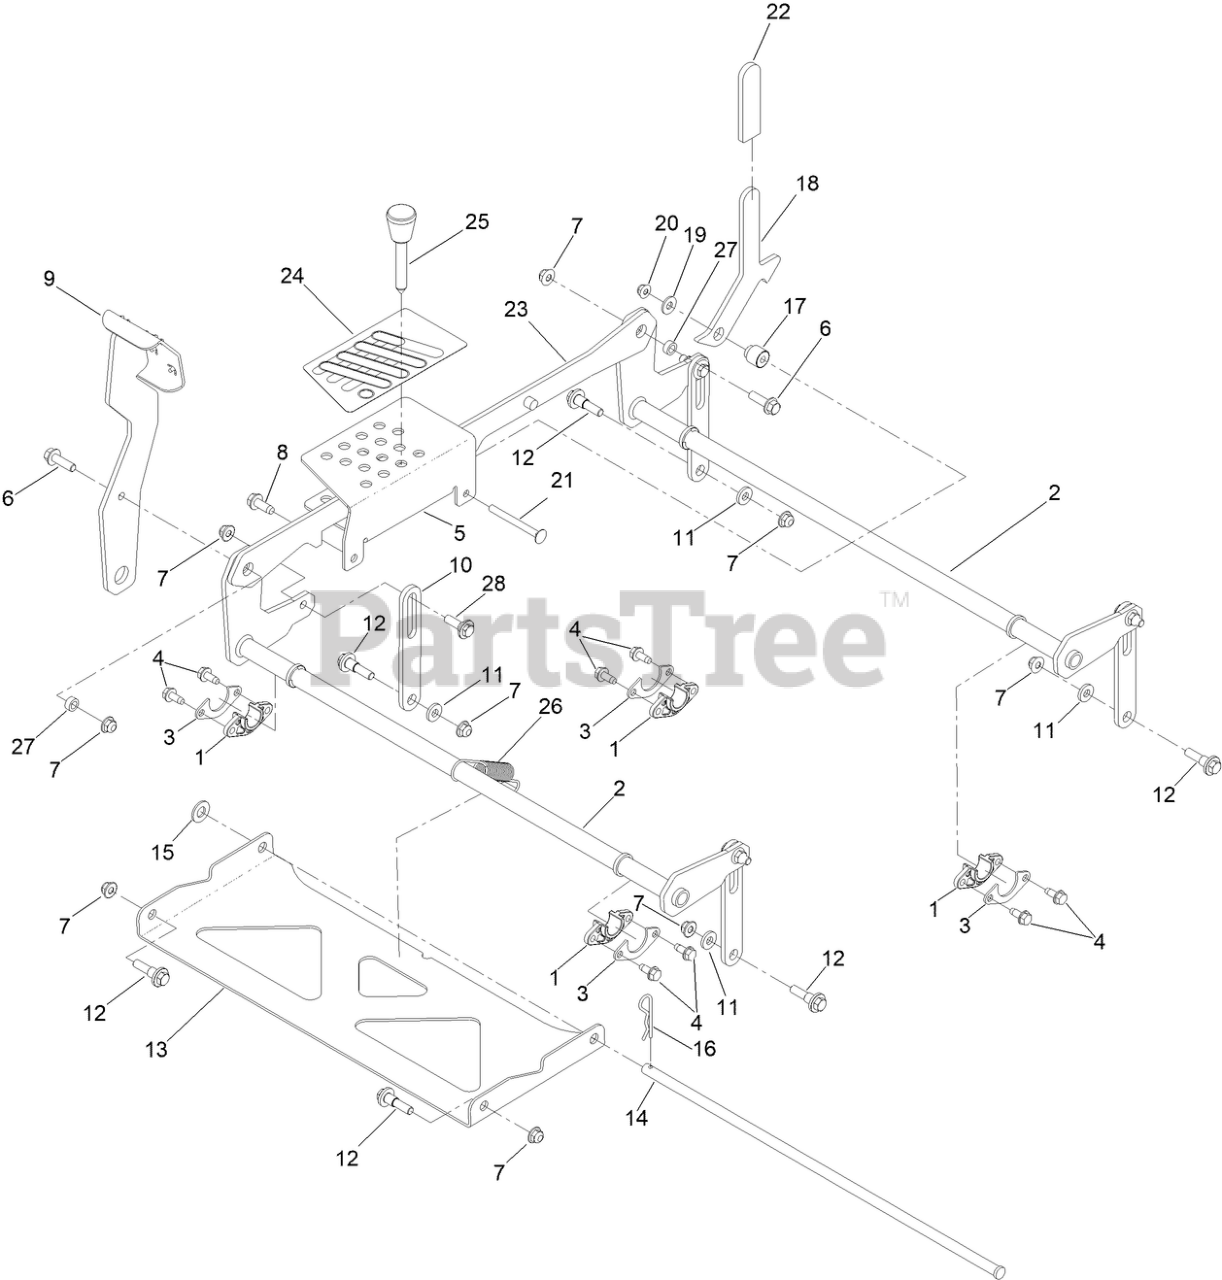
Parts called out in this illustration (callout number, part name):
1	BEARING-FLANGE
2	PIVOT ASM-DECKLIFT [RED]
3	GUSSET-DECK LIFT
4	SCREW-HWHTF
5	BRACKET-HOC
6	SCREW-HHF
7	NUT-HF, NI
8	SCREW-HWH
9	PEDAL ASM [RED]
10	LINK-HOC
11	SPACER-HUB, BLOWER
12	BOLT-SHOULDER
13	PAN-DECK PIVOT
14	PIN-DECK
15	WASHER-FLAT
16	PIN-HAIR
17	SPACER-STEPPED
18	PLATE-TRANSPORT LOCK
19	WASHER-PLAIN
20	NUT-HF
21	SCREW-CARR
22	GRIP-HANDLE
23	LINK ASM-HOC [RED]
24	DECAL-HOC, TITAN
25	HOC PIN ASM
26	SPRING-EXTENSION
27	SPACER
